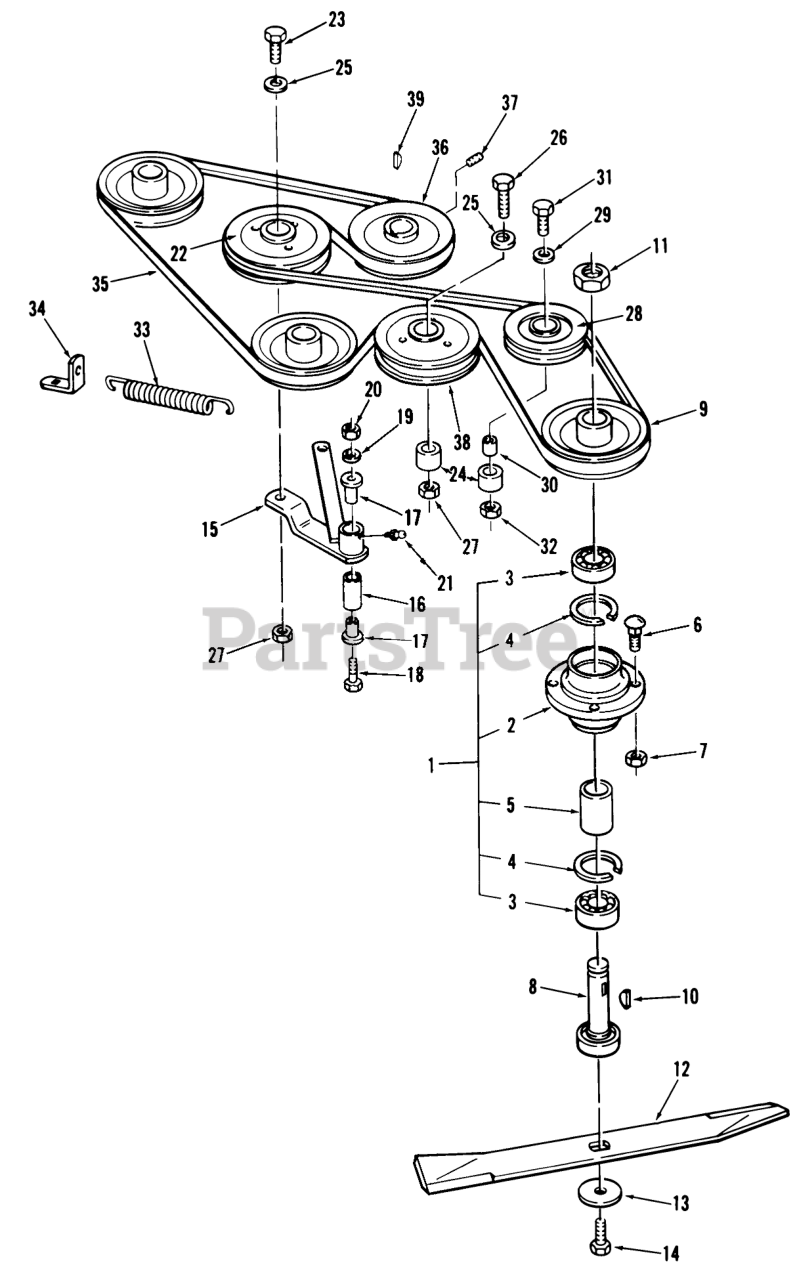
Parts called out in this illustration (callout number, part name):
1	Spindle Housing Assembly
2	Spindle Housing
3	Bearing
4	Snap Ring (Internal)
5	SPACER-SPINDLE
6	Bolt
7	LOCKNUT-FLANGE
8	Spindle Shaft Assembly
9	PULLEY-END
10	WOODRUFF KEY 1/4X7/8
11	Jam Nut 1-14
12	BLADE
13	Drive Washer
14	Bolt
15	ASSY-IDLER ARM
16	Bushing
17	BUSHING
18	Bolt
19	Washer
20	Nut
21	Zerk
22	PULLEY-IDLER
23	BOLT
24	SPACER
25	Washer
26	Bolt
27	Nut
28	PULLEY-V IDLER
29	Washer
30	Spacer
31	Bolt
32	Nut
33	SPRING-EXTENSION
34	Spring Anchor
35	V-BELT, DECK DR.
36	Washer
37	Set Screw
38	PULLEY-IDLER
39	WOODRUFF KEY 1/4X7/8
